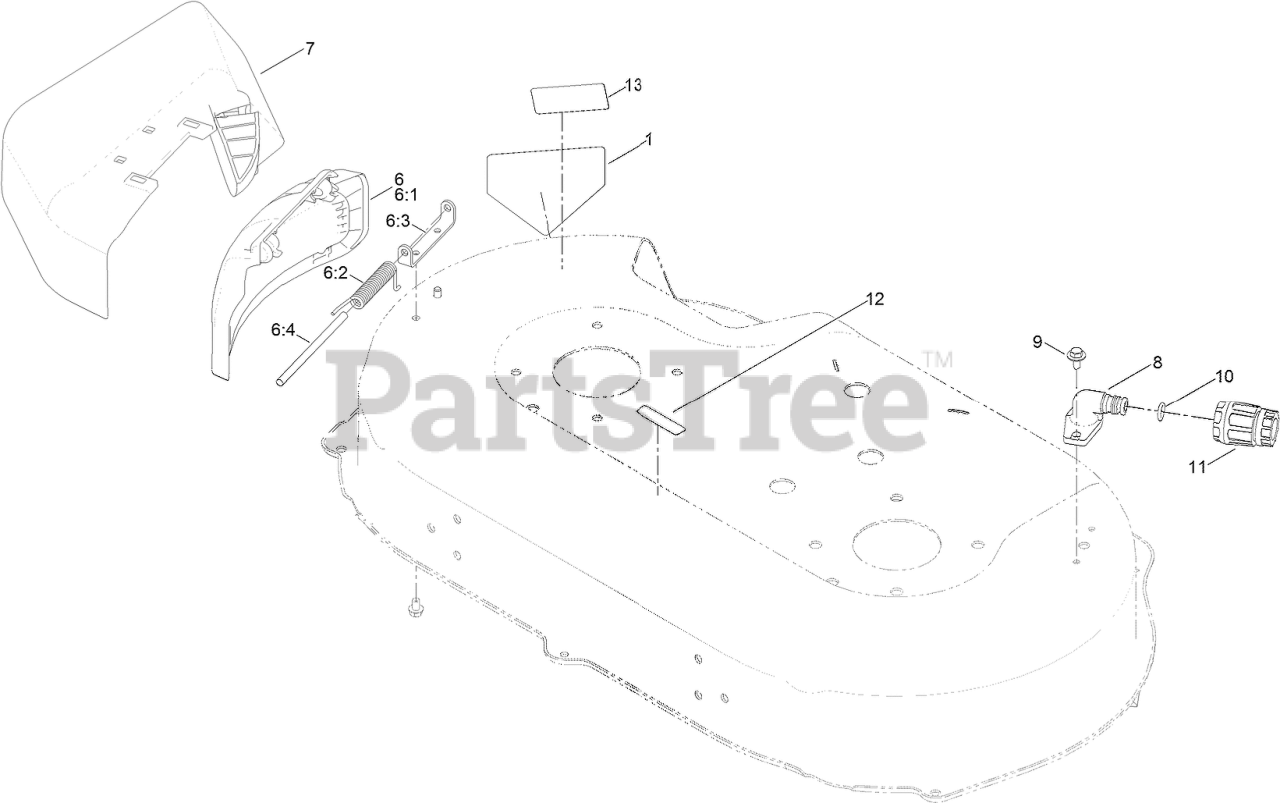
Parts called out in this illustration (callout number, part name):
1	DECAL-DANGER
6	SIDE DEFLECTOR SERVICE ASM
6:1	DEFLECTOR-SIDE
6:2	SPRING-TORSION, COVER
6:3	BRACKET-COVER
7	CHUTE-DISCHARGE, SIDE
8	FITTING-WASHOUT
9	SCREW-HHFTF
10	O-RING
11	CONNECTOR-HOSE
12	DECAL-WARNING
13	DECAL-PLACEMENT, FOOT
